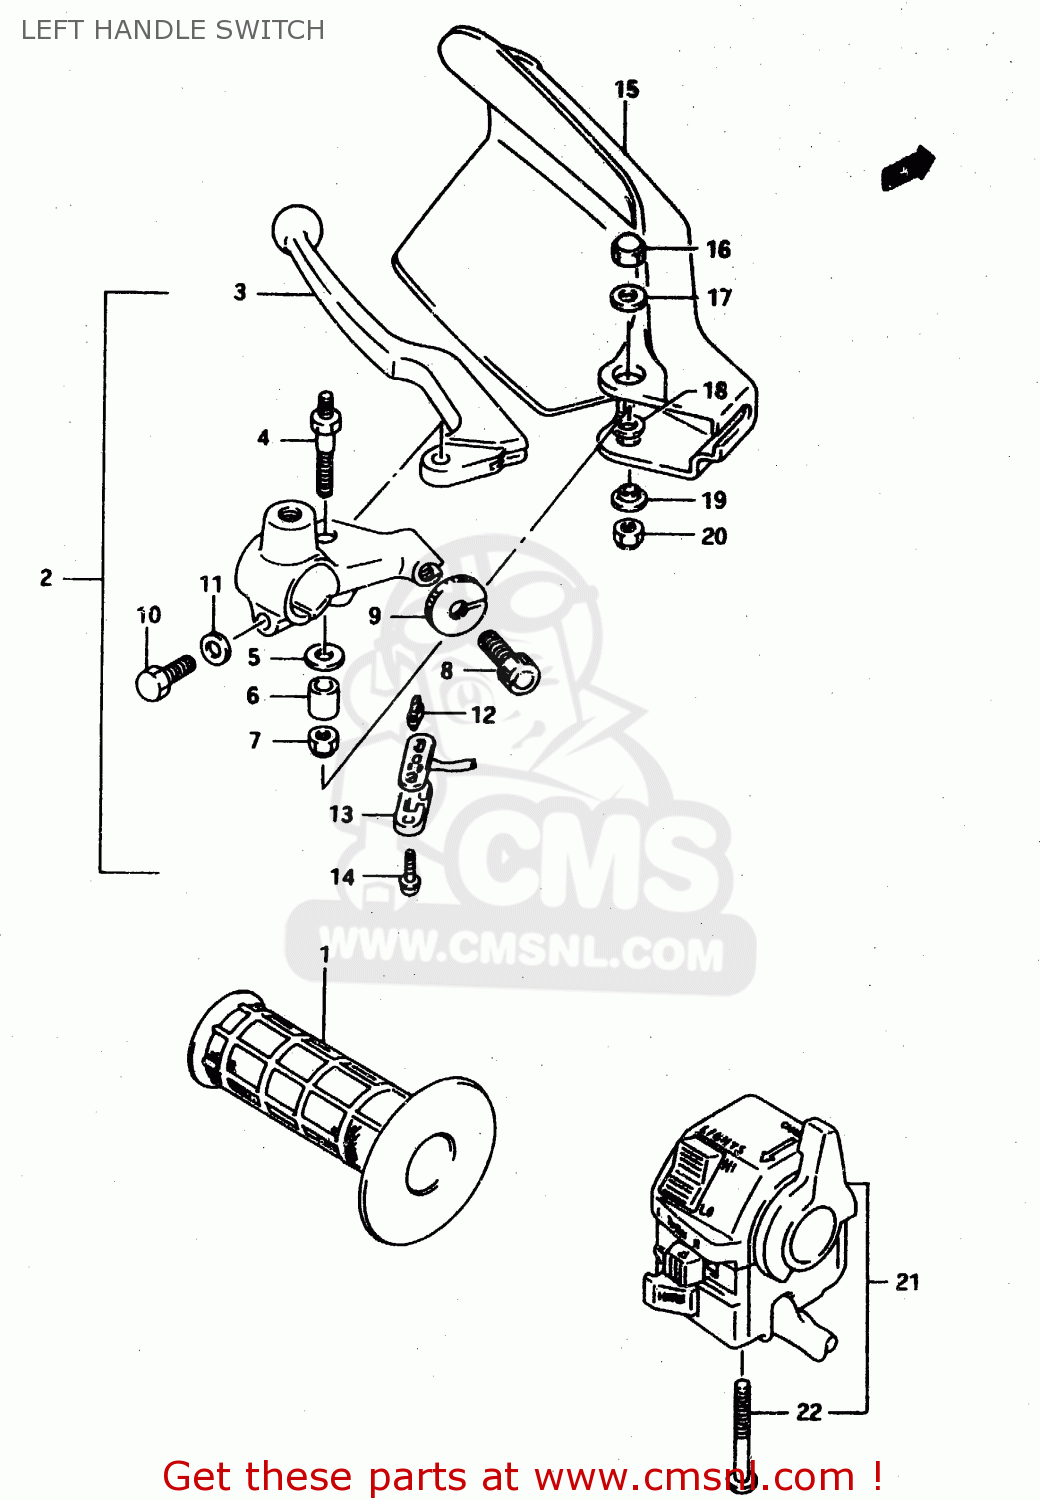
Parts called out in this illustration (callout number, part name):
1	GRIP,L
2	LEVER ASSEMBLY,CLUTCH
3	LEVER,CLUTCH
4	BOLT,LEVER SET
5	WASHER
6	SPACER,LEVER SET
7	NUT
8	ADJUSTER,CABLE
9	NUT,CABLE ADJUSTER
10	BOLT
11	WASHER
12	CONTACT,SWITCH
13	COVER,FR BK TERMINAL BASE
14	SCREW
15	COVER,KNUCKLE,LEFT
16	NUT
17	WASHER(6.5X20X1.6)
18	WASHER(6.5X16X1.2)
19	WASHER
20	NUT 6MM
21	SWITCH ASSY,HANDLE,L
22	SCREW, 5X45
